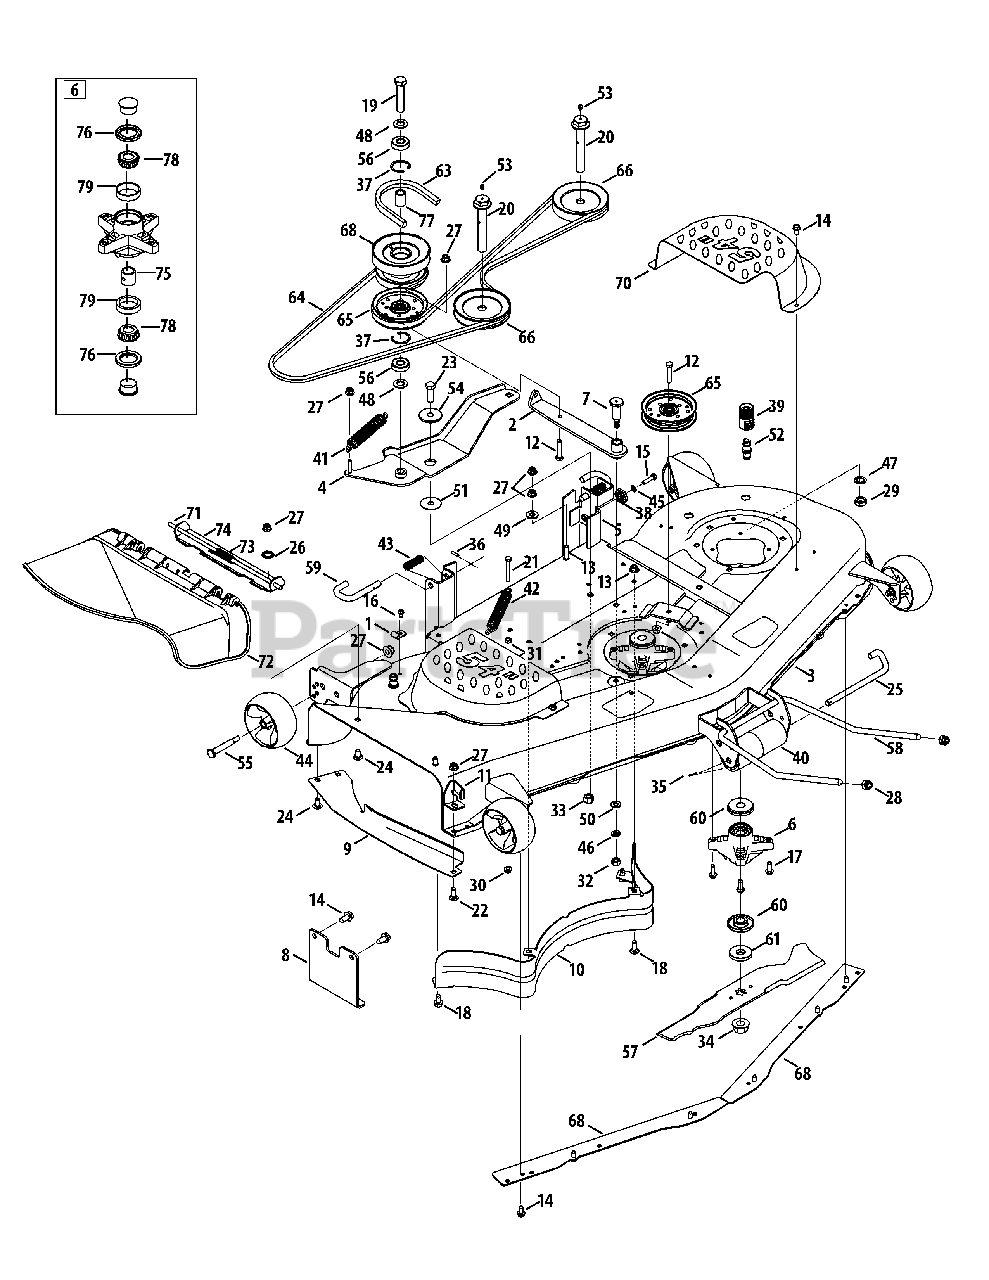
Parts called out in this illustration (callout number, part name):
1	Hook Retainer Bracket
2	Idler Assembly
3	Deck Assembly
4	PTO Idler Assembly
5	Hanger Adjustment Bracket
6	Spindle Assembly
7	Shoulder Bolt
8	Up-Stop Bracket
9	Guard
10	Inner Baffle
11	Chute Deflector Stop
12	Hex Screw, 3/8-16 x :1.75
13	Carriage Bolt, 3/8 x 16 x 1.50
14	Hex Washer Screw, 5/16-18 x .750
15	Hex Screw, 5/16-18 x 1.25
16	Hex Washer Screw, 1/4-20 x .500
17	Hex Washer Screw, 5/16-18 x 1.000
18	Hex Washer Screw, 3/8-16 x .750
19	Hex Screw, 5/8-18 x 3.00
20	Spindle Bolt, 3/4-16 x 5.215
21	Hex Screw, 5/16-18 x 2.25
22	Carriage Bolt, 3/8-16 x 1.00
23	Hex Screw, 1/2-20 x 1.50
24	Carriage Bolt, 3/8-16 x .75
25	Roller Pin, 1/2 x 7.31
26	Push Nut, 3/8
27	Flange Lock Nut, 3/8-16
28	Flex Lock Nut, 1/2-13
29	Hex Nut, M16-1.5
30	Flange Lock Nut, 5/16-18
31	Hex Nut, 5/16-18
32	Hex Nut, 7/16-14
33	Hex Lock Nut, 1/2-20
34	Flange Lock Nut, 3/4-16
35	Cotter Pin, 3/32 x 1.25
36	Spirol Spring Pin
37	Retainer Ring
38	Deck Adjustment Gear
39	Water Nozzle Adapter
40	Front Roller
41	Extension Spring, 1.0 x 6.140
42	Extension Spring, 1.0 x 6.42
43	Compression Spring, .66 x 1.8
44	Deck Wheel, 5.0
45	Lock Washer, 5/16
46	Lock Washer, 7/16
47	Lock Washer, 5/8
48	Flat Washer, .65 x 1.25 x .075
49	Flat Washer, .510 x 1.000 x .125
50	Flat Washer, .469 x .875 x .105
51	Flat Washer, .535 x 1.92 x .060
52	Deck Water Nozzle
53	Drive Lube Fitting, 3/16
54	Shoulder Spacer, .9790 x .2025
55	Shoulder Screw, 1/2 x 2.50
56	Ball Bearing, .625 x 40 x 12
57	Blade QTY-3, round hole
57	Blade QTY-3
58	Front Lift Rod
59	Mower Support Pin
60	Deck Spindle Spacer
61	Blade Spacer, 2 x .75 x .31
64	Deck Belt
65	Idler Pulley
66	Spindle Pulley
67	Double Pulley
69	RH Belt Cover
70	LH Belt Cover
71	Hinge Pin, .3175 x 14.06
72	Chute Deflector
73	Torsion Spring, .44 x 2.0
74	Chute Bracket
75	Bearing Spacer, .78 x 1.0 x 1.0425
77	Spacer, .88 x .635 x 1.25
78	Cone Bearing, .750
79	Bearing Cup, .750
